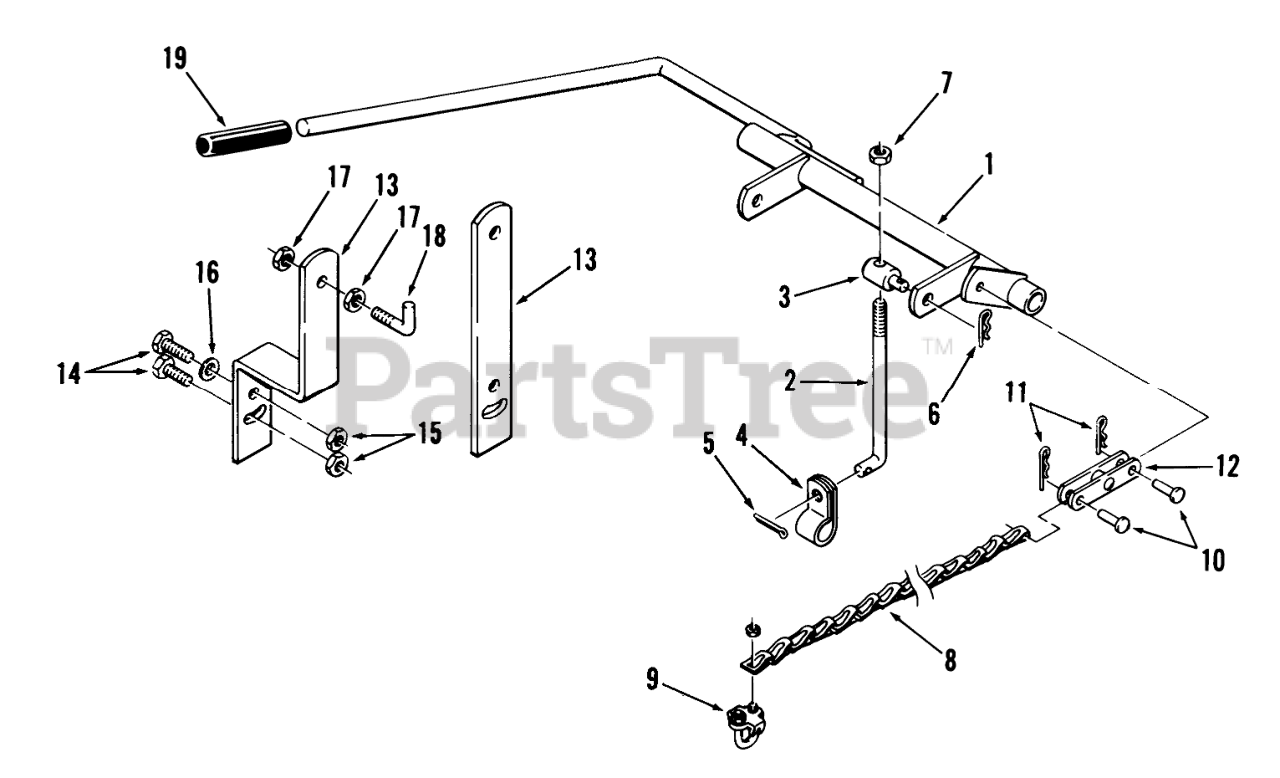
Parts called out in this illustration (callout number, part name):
1	Lift Lever Assy.
2	Lift Rod
3	TRUNNION-LIFT
4	Clamp
5	Cotter Pin
6	Hairpin
7	Nut
8	Chain
9	Cable Clamp
10	Pin
12	ASSEMBLY CLEVIS
13	Bracket-36 in. (92 cm) Mower
13	Bracket-42 in. (107 cm) Mower
14	BOLT
15	Nut
16	Washer
17	Nut
19	GRIP
